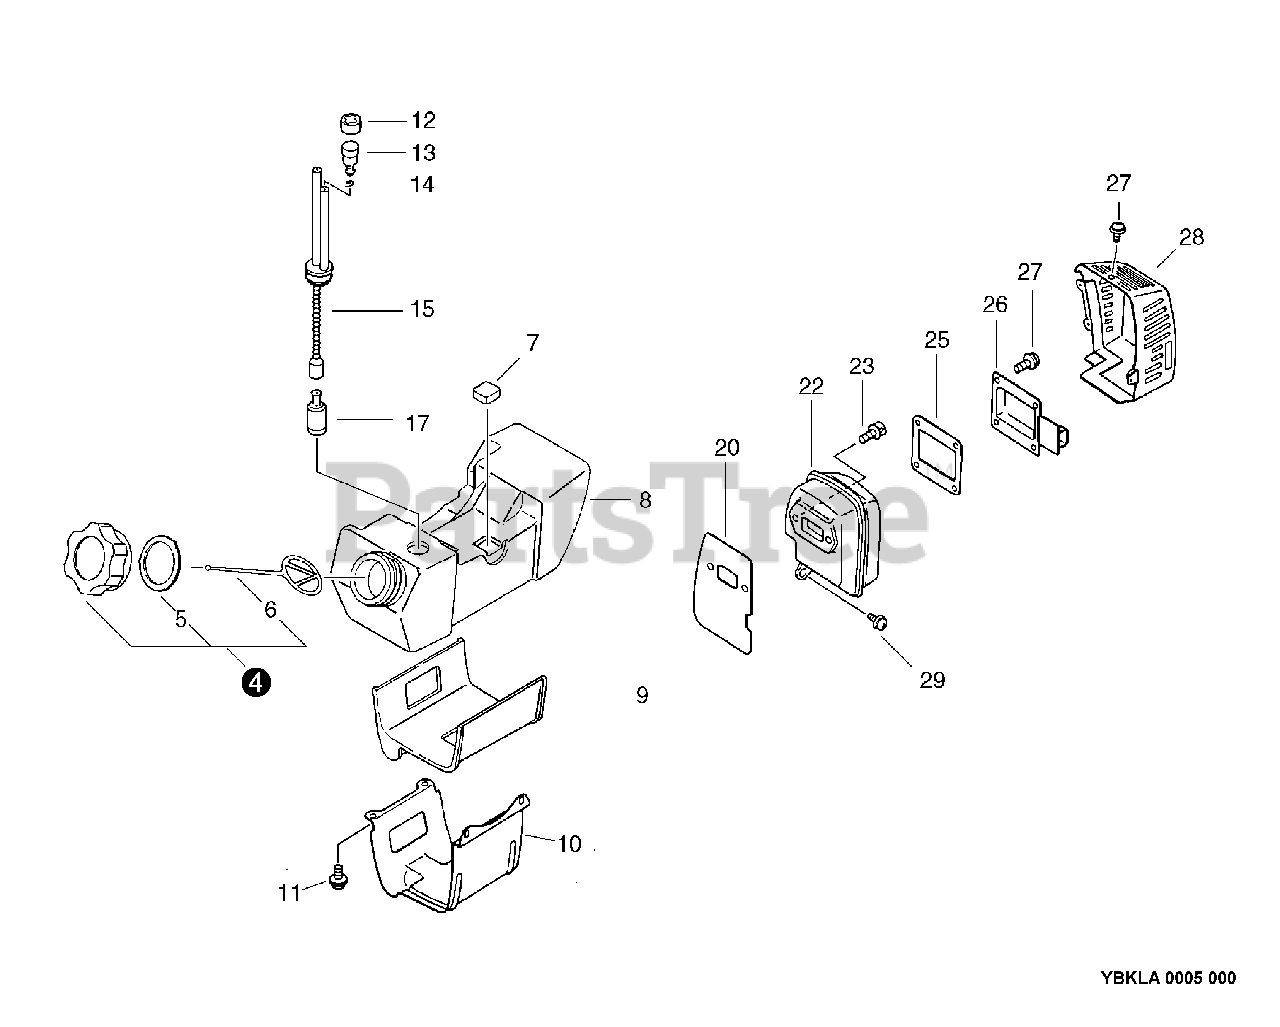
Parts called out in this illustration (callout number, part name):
4	CAP ASSY - ORANGE
5	GASKET, CAP
6	CONNECTOR, CAP
8	TANK, FUEL
10	BRACKET, FUEL TANK
11	SCREW - 5X14
12	COVER, VENT
13	VENT, FUEL TANK
14	CLIP - 6.5
15	FUEL PIPE ASSY
17	FILTER, FUEL
20	GASKET, EXHAUST
23	SCREW - 5X20
25	GASKET, EXHAUST
26	GUIDE, EXHAUST
27	SCREW - 4X10
28	GASKET, EXHAUST
29	SCREW - 5X14
